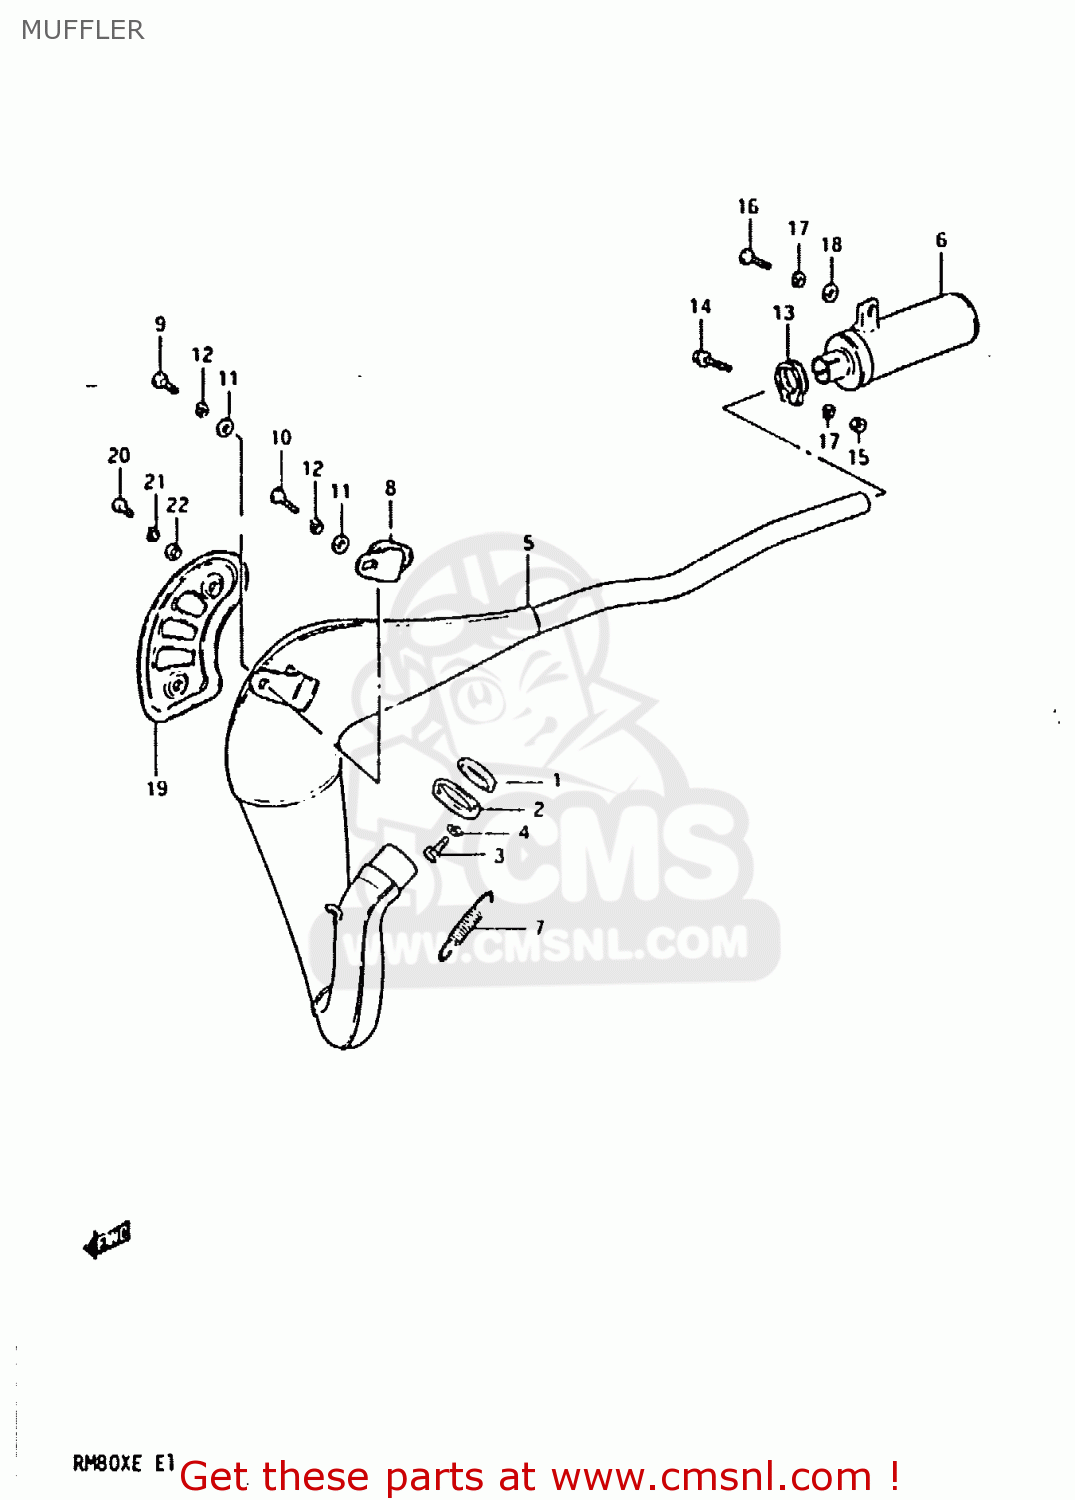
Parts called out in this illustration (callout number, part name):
1	GASKET,EXHAUST PIPE (NAS)
2	CLAMP,EXHAUST PIPE
3	BOLT 6X16
4	LOCK WASHER
5	BODY,MUFFLER
6	MUFFLER, 2ND
7	SPRING
8	DAMPER,MUFFLER SUPPORT
9	BOLT
10	BOLT, UPPER
11	WASHER
12	LOCK WASHER
13	CLAMP,EXHAUST
14	BOLT
15	NUT 6MM
16	BOLT
17	LOCK WASHER
18	WASHER
19	COVER,MUFFLER
20	SCREW
21	LOCK WASHER
22	WASHER
